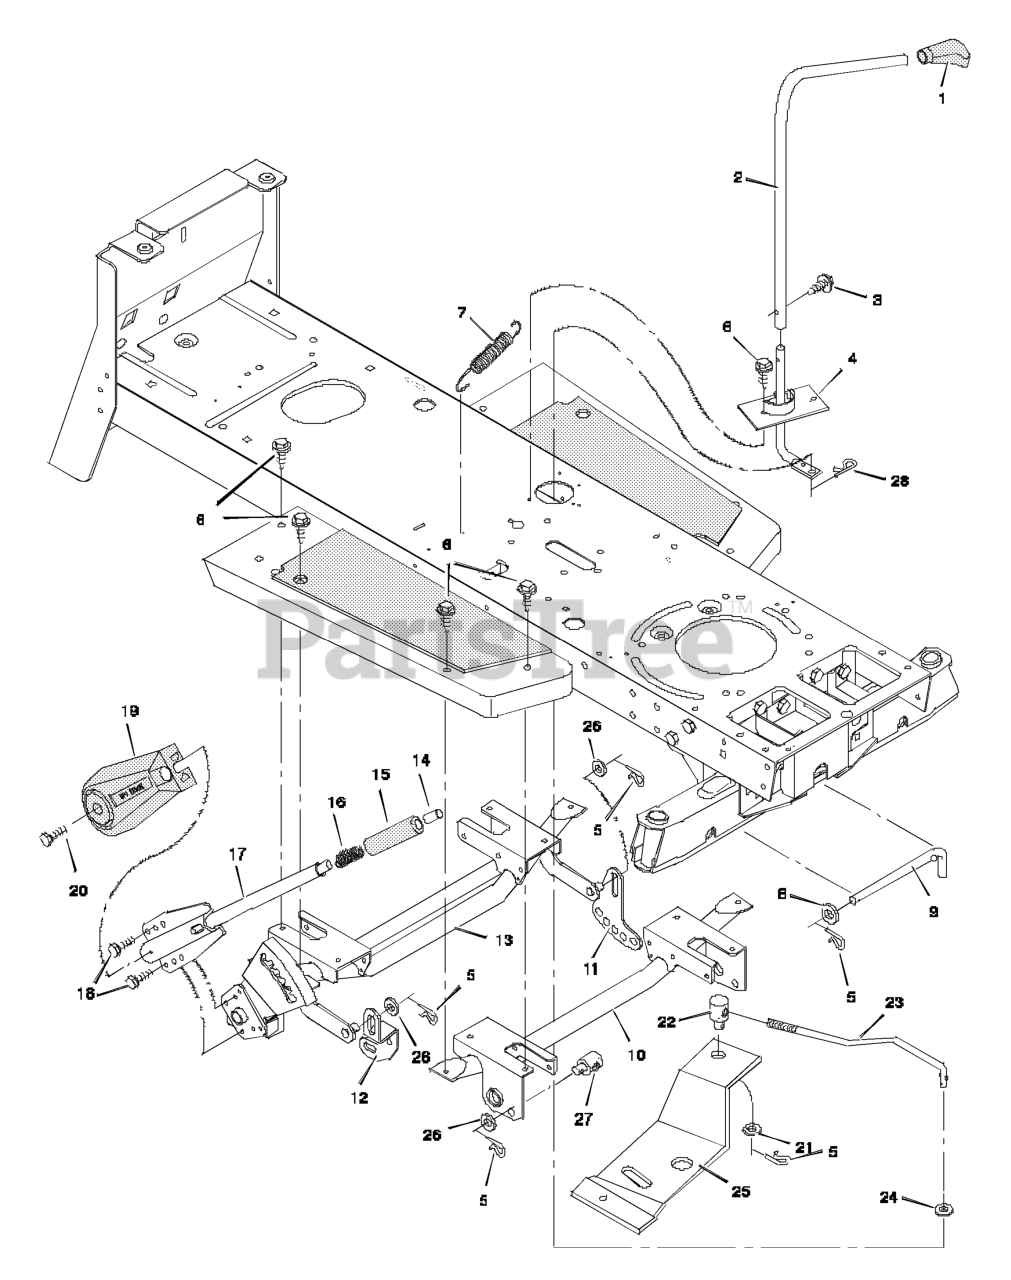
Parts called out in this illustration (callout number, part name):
1	Grip
2	Lever, Blade Control
3	Screw, Hex
4	Control Assembly, Blade
5	Pin, Hair
7	Spring, Extension
9	Pin, Pull
10	Support Assembly, Front
11	Plate, Adjuster
12	Link, Suspension
13	Support, Lifter
14	Button, Push
16	Spring, Compression
17	Handle Assembly
19	Cover, Lift Lever
22	Nut, Adjusting
23	Rod, Blade Control
24	Washer
25	Bracket, Pivot
27	NUT, Adjusting, 1/2-13
28	Pin, Hair
